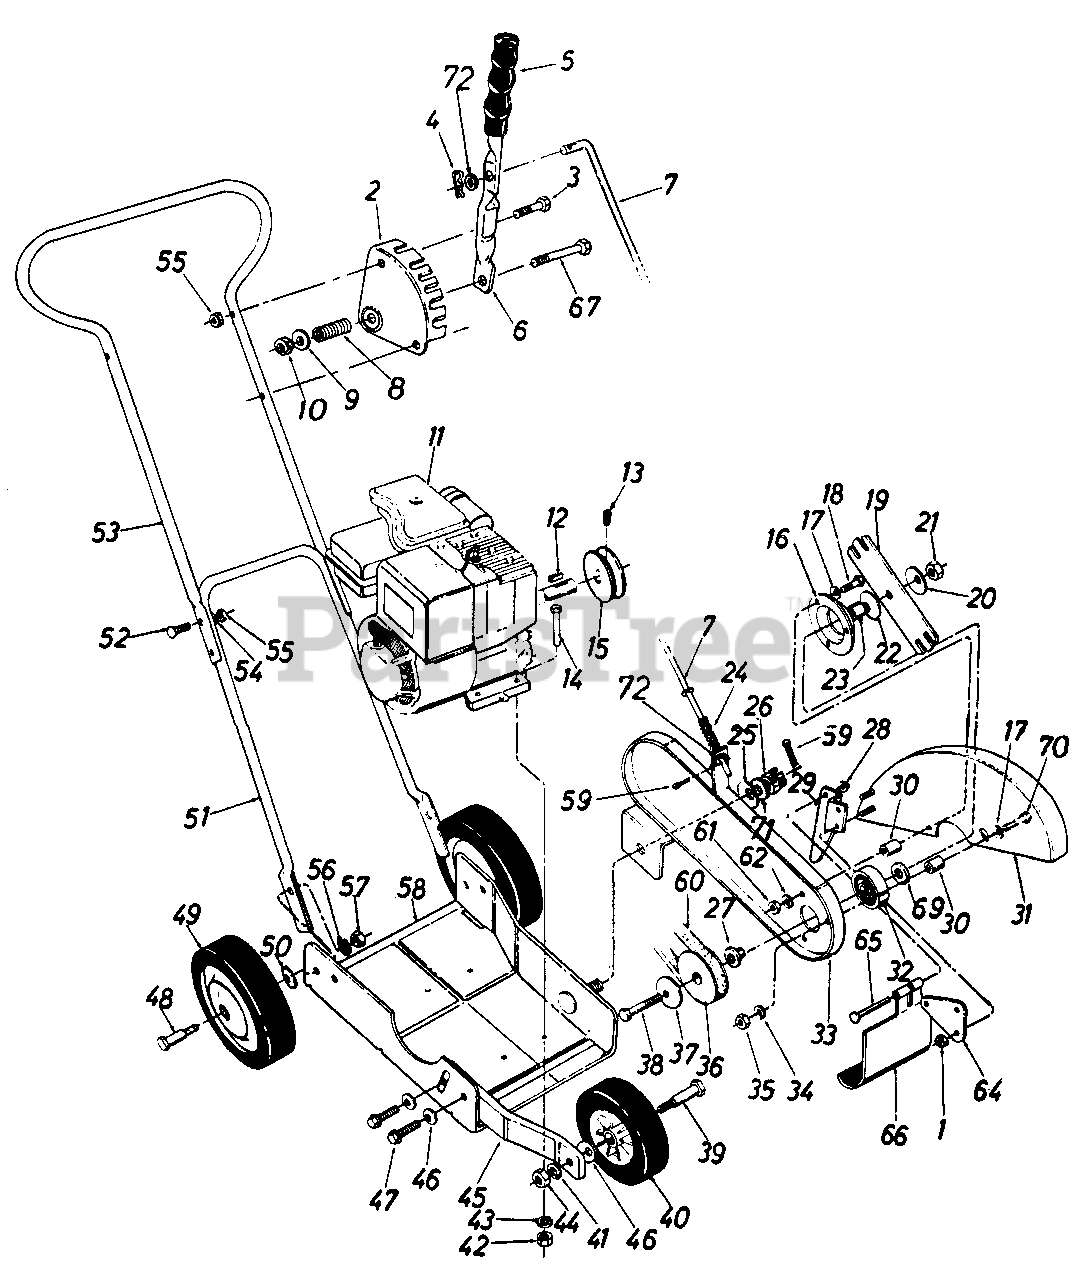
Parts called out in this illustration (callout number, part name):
1	Hex Cent. L.-Nut 1/4-20 Thd.
3	Hex Bolt 1/4-20 x 1.25" Lg.
4	Cotter Pin 1/8" Dia. x 1.0" Lg.
5	Grip
7	Clutch Rod
8	Compression Spring .50" O.D. x 1.38" Lg.
9	Fl.-Wash. .34" I.D. x .62" O.D. x.063
10	Hex Cent. L.-Nut 5/16-18 Thd.
11	Engine
12	Sq. Key 3/16 x 1.0" Lg.
13	Set Scr. 1/4-28 x 1/4" Lg.
14	Hex Bolt 5/16-18 x 1.50 ' Lg.
15	Engine Pulley
16	Bearing Housing
17	Bell.-Wash. .34' I.D. x 88" O.D. x .060
18	Hex Bolt 5/16-18 x 1.25" Lg.
20	Bell.-Wash. .535" I.D. x 1.50" O.D. x.052
21	Hex Cent. L.-Nut 1/2-20 Thd.
22	Bell.-Wash. .535" I.D. x 1.50" O.D. x.052
23	Spacer
24	Compression Spring .57" O.D. x 1.92" Lg.
25	Bell.-Wash. .535" I.D. x 1.50" O.D. x .052
26	Hex Castle Nut 1/2-20 Thd.
27	Shoulder Spacer
28	Push Cap
29	Guide
30	Spacer.354" I.D. x.635" O.D. x.510" Lg.
33	Spindle Bracket Ass'y.
34	L.-Wash. 5/16" I.D.
35	Hex Nut 5/16-18 Thd.
36	Pulley Half
37	Bell.-Wash. .535" I.D. x 1.50" 0 D. x .052
38	Hex Bolt 1/2-20 x 3.50" Lg.
39	Shoulder Bolt .498" Dia. x 1 .450
40	Wheel Ass'y. Comp. 6" Dia. x 1.50
41	L.-Wash. 3/8" I.D.
42	Hex Nut 5/16-18 Thd.
43	L.-Wash. 5/16" I.D.
44	Hex Nut 3/8-16 Thd.#
45	Front Wheel Support
46	Bell.-Wash. .400" I.D. x 88" O.D. x.060
47	Hex Wash. Hd. Self Tap Scr. 3/8-16 x .75" Lg.
48	Shoulder Bolt .498" Dia. x 1 .450
49	Wheel Ass'y. Comp. 7" Dia. N x 1.50
50	Bell.-Wash. .400" I.D. x 88" 0. D.
51	Lower Handle
52	Carriage Bolt 1/4-20 x 1.25" Lg.
53	Upper Handlc
54	L.-Wash. 1/4" I.D.
55	Hex Nut 1/4-20Thd.
56	L.-Wash. 3/8" I.D.
57	Hex Nut 3/8-16 Thd.
58	Base Ass'y.
59	Cotter Pin 1/8" Dia. x 1.0" Lg.
60	3V-Belt 31.2" Lg.
61	Hex Nut 5/16-18 Thd.
62	L.-Wash. 5/16" I.D.
64	Flap Bracket
65	Hinge Pin
66	Debris Deflector
67	Hex Bolt 5/16-18 x 1.75" Lg.
69	Fl.-Wash. .51 I.D. x 1.00 O.D. x .060
70	Hex Bolt 5/16-18 x 2.00"
71	Fl-Wash. .53" I.D.
72	Fl-Wash. 3/8" I.D.
